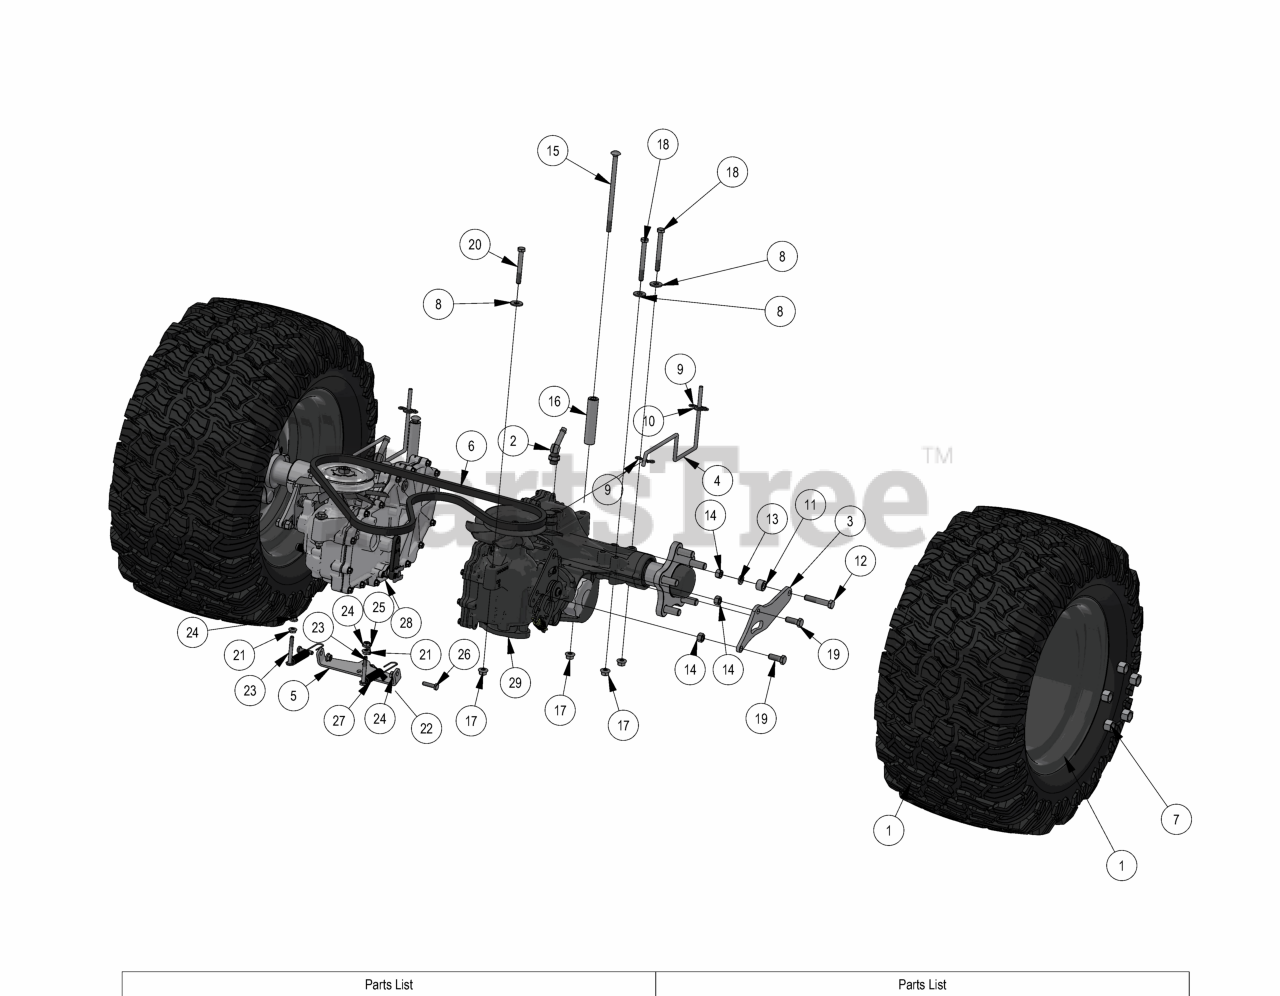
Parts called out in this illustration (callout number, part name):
1	23x11-12 Reaper Turf Assembly
2	ZT Fitting, 3/8 x 3/8 45 Degree, 4603-6-6
3	Control Arm Plate 2019 Stand On
4	2019 Stand On Neutral Rod
5	Brake Bracket
6	2019 Stand On Pump Belt (Timken# 47-2827)
7	Acorn Lug Nut
8	5/16 USS FLAT WASHER (7/8 OD) ZINC
10	1/4 USS FLAT WASHER (3/4 OD) ZINC
11	ACS Spacer 3/4x3/8x1/2
12	3/8-16 X 2 HEX CAP SCREW (GR.5) ZINC
13	3/8 SPLIT LOCKWASHER ZINC
14	3/8-16 HEX NUT ZINC
15	5/16-18 X 6 CARRIAGE BOLT (GR.5) ZINC
16	2017 Transaxle Spacer
17	5/16-18 NYLON INSERT FLANGE LOCKNUT ZINC
18	5/16-18 X 3 HEX CAP SCREW (GR.5) ZINC
19	3/8-16 X 1 GR 5 Hex Bolts Zinc
20	5/16-18 X 2-1/2 HEX CAP SCREW (GR.5) ZINC
21	1/4-20 HEX SERRATED FLANGE NUT HARD/ZINC
22	1/4-20 NYLON INSERT LOCKNUT ZINC
23	1/4-20 X 2 HEX CAP SCREW (GR.5) ZINC
24	1/4-20 NYL INSERT FLANGE LOCKNUT ZINC
25	1/4-20 X 3/4 HEX CAP SCREW (GR.5) ZINC
26	1/4-20 X 1 HEX CAP SCREW (GR.5) ZINC
27	Brake Spring
28	Compact Outlaw/Revolt Transaxle Right
29	Compact Outlaw/Revolt Transaxle Left
